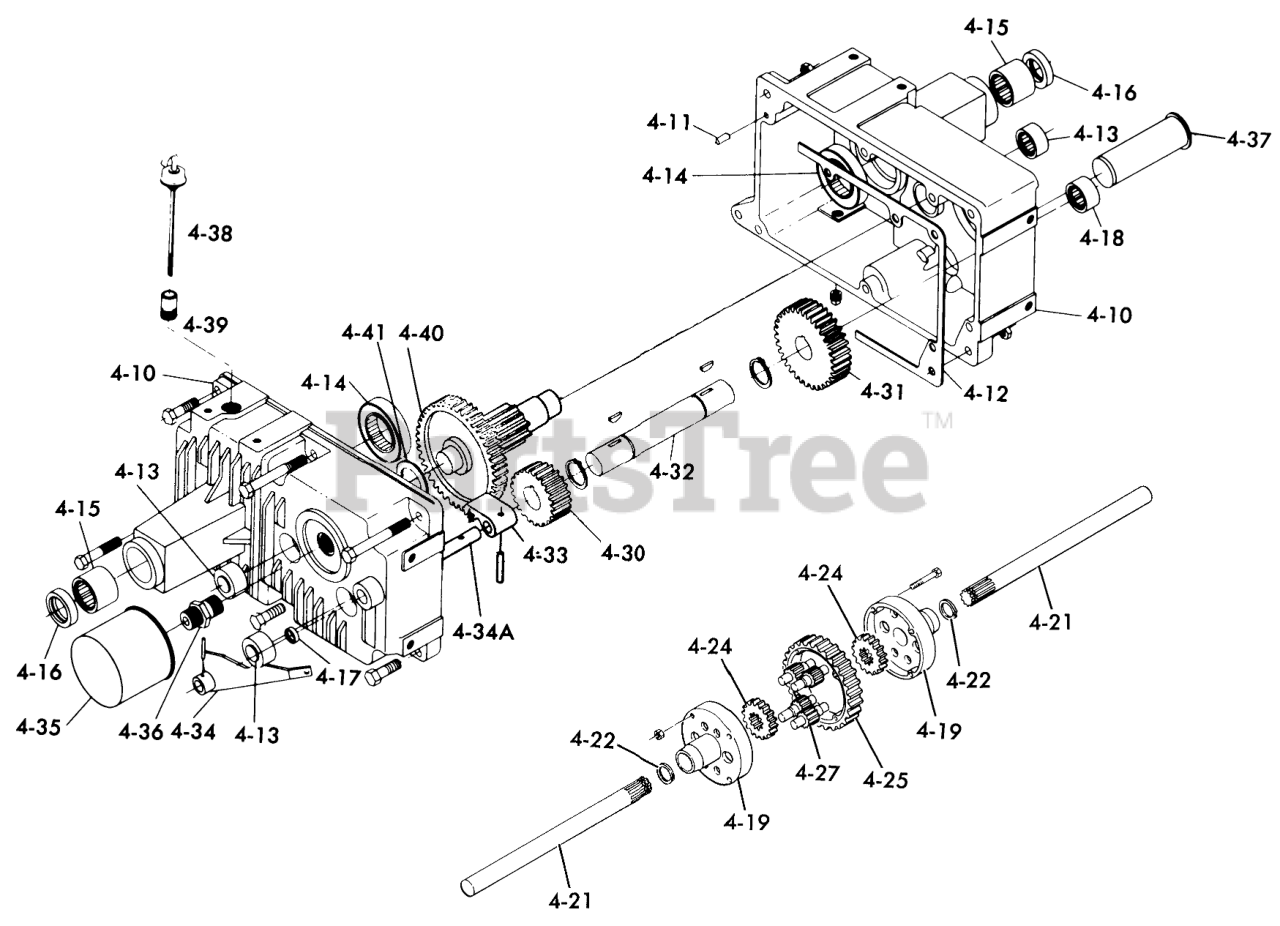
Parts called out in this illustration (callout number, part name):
4-10	Case RH
4-11	PIN-DOWEL
4-13	BEARING-NEEDLE
4-15	BEARING-NEEDLE
4-19	SVCBULLT 394
4-24	AXLE GEAR
4-25	SVC BULLT 394
4-27	GEAR-PINION, 11T
4-30	GEAR 24T
4-36	FITTING
4-41	WASHER-THRUST
